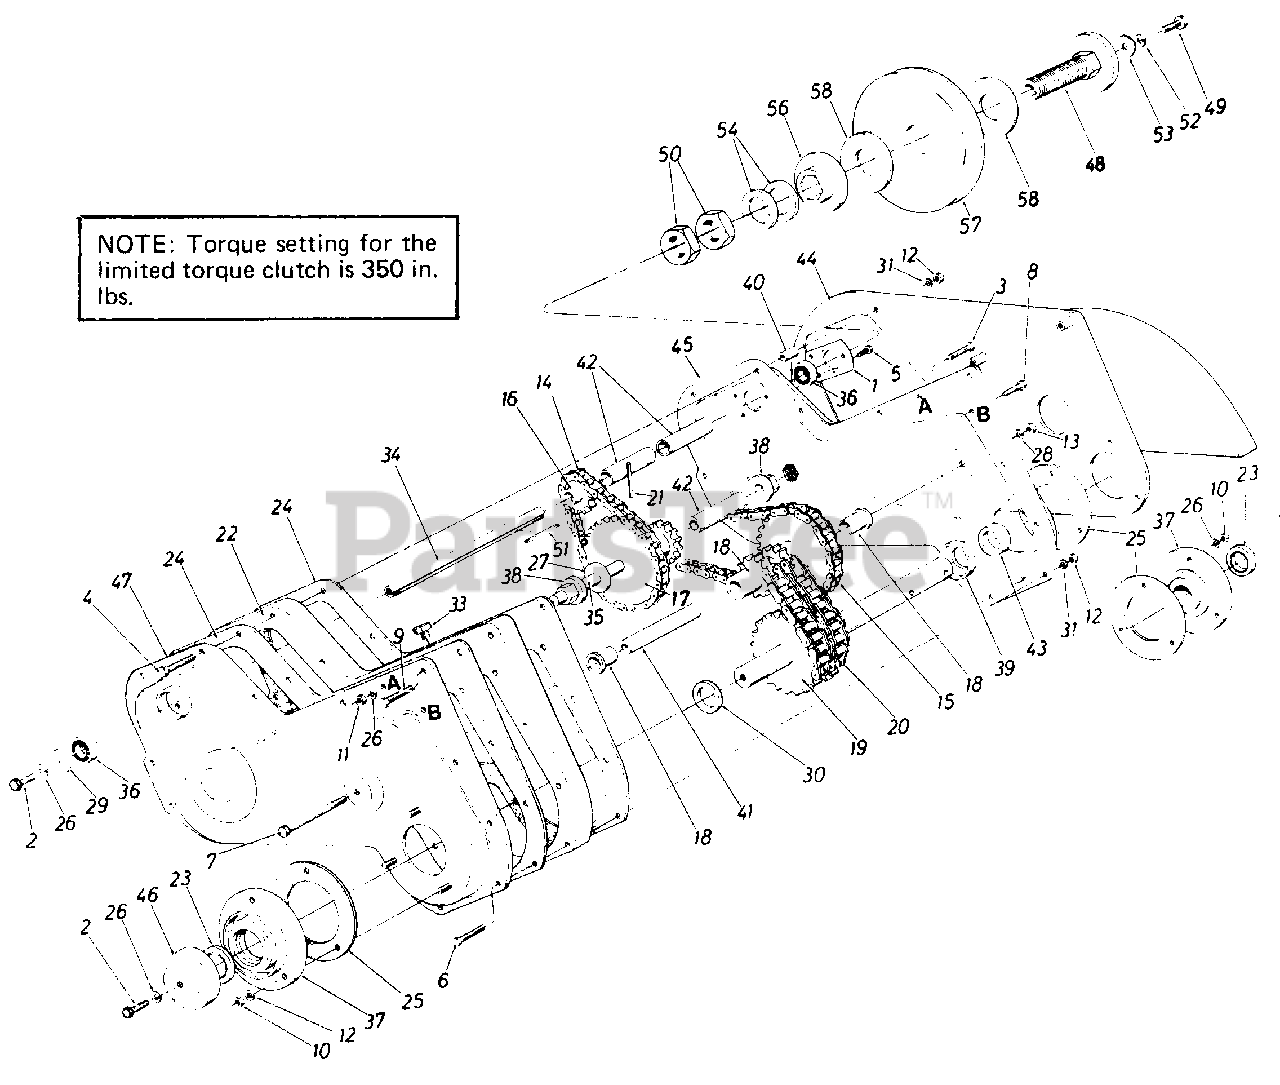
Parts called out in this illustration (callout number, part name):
1	Bearing Housing 1-3/8" Dia.
2	Hex Bolt 5/16-18 x .88" Lg. Spec.
3	Hex Bolt 5/16-18 x 1.50" Lg.
4	Hex Bolt 1/4-20 x 2.75" Lg.'
5	Hex Wash. S-Tap. Scr. 1/4-20 x .50" Lg.
6	Hex Bolt 1/4-20 x 1.50" Lg.
7	Hex Bolt 3/8-16 x 4.5" Lg. 1.5" Lg
8	Hex Wash Hd.Bolt 1/4-20 x 1.5" Lg.
9	Hex Wash. TT-Tap Scr. 5/16-18 x1.75" Lg.
10	Hex Cent. L.-Nut 5/16-18 Thd.
11	Hex Nut5/16-18 Thd.
12	Hex Nut 1/4-20 Thd.
13	Hex Nut 3/8-16 Thd.
14	#41 Chain 1/2" Pitch x 34 Links-Endless
15	#42 Chain 1/2" Pitch x 48 Links-Endless
16	Sprocket 10 Tooth .500" Pitch
17	10 & 28 Teeth Sprocket Ass'y.
18	8-2 & 28 Sprocket Sleeve Ass'y
19	18-2 Sprocket Shaft Ass'y.
20	#50-2 Chain 5/8" Pitch x 28 Links-Endless
21	Spring Pin Spir. 1/4" Dia. x 1.50" Lg.
22	Spacer Block Tiller Housing
23	Oil Seal Double Lip-1-1/4" Dia.
24	Gasket for Tiller Housing
25	Gasket for Brg.-Housing
26	L.-Wash. 5/16" I.D.
27	Fl.-Wash. .640" I.D. x 1.24" O.D.
28	L.-Wash. 3/8" I.D. Heavy Duty
29	Fl.-Wash. .344" I.D. x 1.125"
30	Special Washer
31	L.-Wash. 1/4" I.D.
33	Vent Plug
34	JackShaft .525" I.D. x 7.78" Lg.
35	Sprocket Shaft .63" Dia. x 5.0" Lg.
36	Ball Brg. .62" I.D. x 1.38" O.D.
37	Bearing Housing 1-1/4"
38	Hex Flange Brg.
39	Spacer 1.25" I.D. x 2.0" O.D.
40	Spacer.28" I.D. x .62" O.D. x .90" Lg.
41	Spacer .38" I.D. x .62" O.D. x 3.44" Lg.
42	Spacer.62" I.D. x .88" O.D. x 1.56" Lg.
43	Spacer 1.25" I.D. x 1.62" O.D. x.50" Lg.
46	Dust Cap .320" Dia. Hole
49	Hex Bolt 5/16-18 x 1.25" Lg. Grade 5
50	Hex Jam Nut 1.0-14 x 28 Thd.
51	Sq. Key 3/16 x 1.50" Lg.
52	L.-Wash. 5/16" I.D.
53	Fl.-Wash. .344" I.D. x 1.125" O.D.
54	Spring Bell Wash. 1.0" I.D. x 2.0 O.D.
56	Floating Disc 3-1/4" O.D. x 1.0" I.D.
57	5/8 V-PulleY 1.50" I.D. x 6.50"
58	Friction Pad 3-1/4" O.D. x 1-3/8" I.D.
